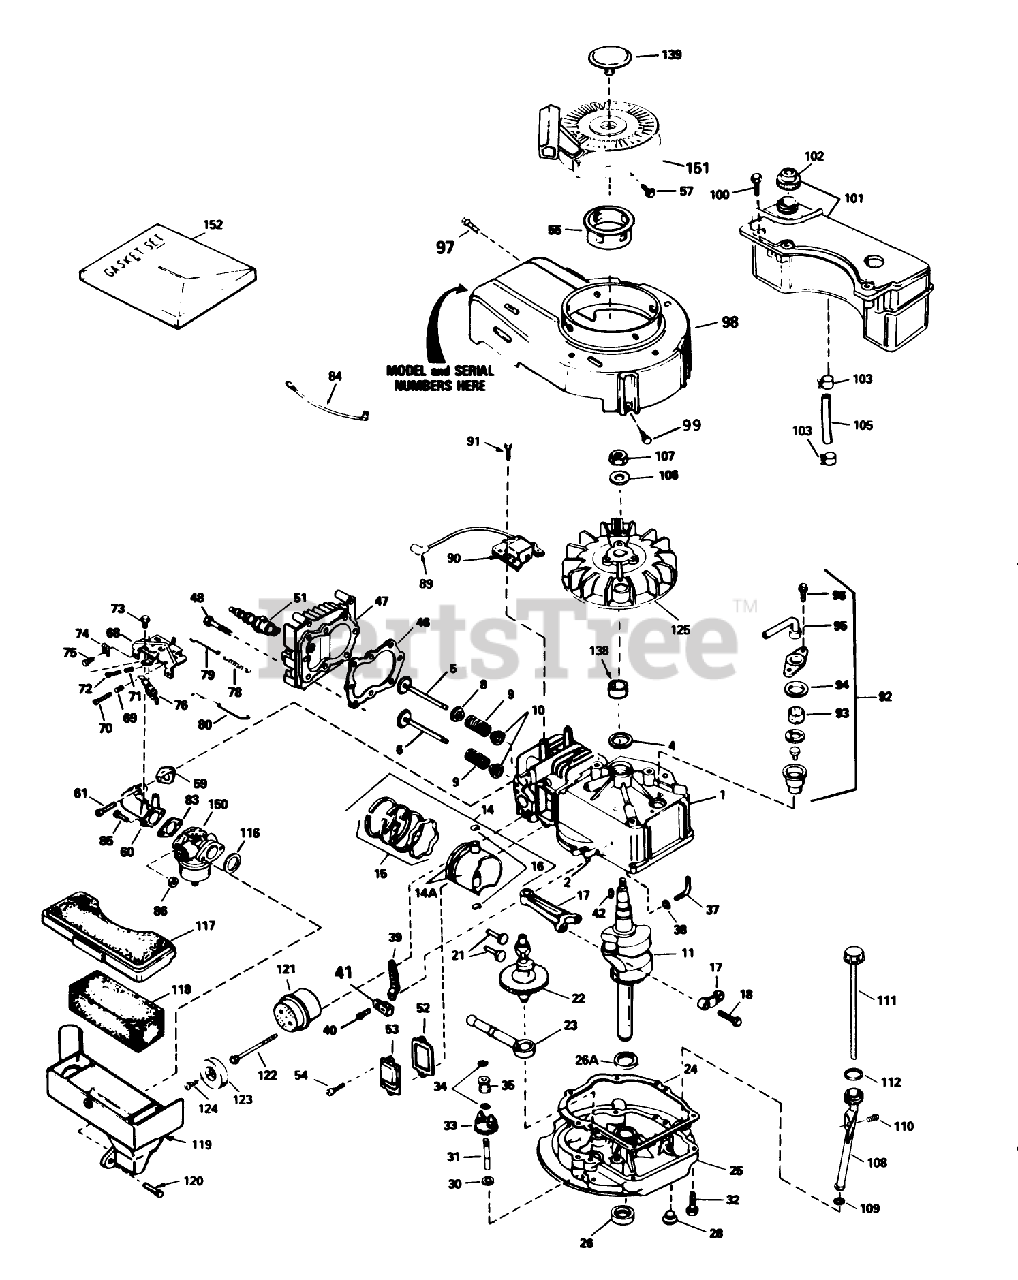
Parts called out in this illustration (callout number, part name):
1	Cylinder Assy. (Incl. #24)
2	Pin-Dowel
4	Seal-Oil
5	Valve, Intake (Std.) (Incl. Ref. #40)
5	Valve, Intake (1/32" oversize)(Incl. No. 40)
6	Valve, Exhaust (Std.)(Incl. No. 40)
6	Valve, Intake (1/32" oversize)(Incl. No. 40)
8	Seal Assy., Intake
9	Spring-Valve
10	Cap-Valve, Spring
11	Crankshaft
14	Piston-Pin Ring Assy. (Std.)(Incl. Ref. #16A, 17 18)
14	Piston-Pin Ring Assembly (.010 oversize)(Incl. Ref. #16A, 17 18)
14	Piston, Pin Ring Assy. (.020 Oversize)(Incl. Ref. #13A, 14, 15)
14A	Piston Pin Assy. (Std.)(Incl. Ref. #14)
14A	Piston Pin Assembly (.010 oversize)(Incl. Ref. #18)
14A	Piston Pin Assy. (.020 Oversize) (Incl. Ref. #14)
15	Ring Set-Piston (Std.)
15	Ring Set, Piston(.0100versize)
15	Ring Set (.020" OS)
16	Ring-Retaining, Piston Pin
17	Rod Assy., Connecting (Incl. Ref. #17)
18	Bolt-Rod, Connecting
21	Lifter-Valve
22	Camshaft(Mech.Comp. Release)
23	Oil Pump ASM
24	Gasket
25	Flange-Mounting (Incl. Ref. #26, 27 39)
26	Seal-Oil
26A	Washer-Thrust
28	Plug Oil Drain
30	Washer-Flat
31	Shaft-Governor
32	Screw (1/4-20 x 1-1/4)
33	Governor Gear ASM
34	Ring-Retaining
35	Spool-Governor
37	Rod, Governor (Incl. No. 36)
38	Washer-Flat
39	Governor Lever
40	Screw
41	Clamp-Lever, Governor
42	Key-Flywheel
46	63573 GIL 42 SNWTHW
47	Head-Cylinder
48	Screw (5/16-18x1-1/2)
51	Spark Plug-Resistor (R J19 L M)
52	Gasket-Breather
53	Cover-Valve
54	Screw
55	Hub-Starter
57	Screw, Hex Hd.
59	Gasket-Intake
60	Pipe-Intake (Incl. Ref. #59)
61	Screw (1/4-20 x 1)
68	Control Assy.-Remote Speed (Incl. Ref. #69 thru 72 76)
69	61709/GIL1515A/95-5
70	Screw
71	Spring-Compression
72	Screw
73	Screw (10-24 x 9/16)
74	Conduit
75	Screw (10-32 x 3/8)
76	Terminal
78	Spring Governor
79	2035A67 ADD.ASSEMBL
80	Link-Throttle
83	Gasket
84	Wire-Ground
86	Nut and Lock Washer (1/4-28)
89	Cover-Spark Plug
90	Solid State
91	Screw
92	Breather Assy. (Incl. Ref. #46 thru 51)
93	Element-Breather
94	Gasket-Breather
95	Tube, Breaker
96	Screw (10-24 x 9/16)
97	Screw (10-24 x 9/16)
98	Housing-Blower
99	Screw (1/4-20 x 1/2)
100	Screw (10-32 x 35/64)
101	Tank Assembly-Fuel (Incl. Ref. #102)
102	Cap-Fuel
103	Clamp-Line, Fuel
105	Line-Fuel
106	Washer-Belleville
107	Nut-Flywheel
108	Oil Fill Tube
109	Gasket
110	Screw (10-32 x 1/2)
111	Dipstick
112	55063 SNWTHWR ADD.W
116	Gasket-Cleaner, Air
117	Cover-Air Cleaner
118	Filter-Air Cleaner
119	Body Air cleaner
120	Screw
121	B Muffler (Incl. Ref. #122)
122	Screw
123	Cover-Muffler
124	Screw (8-32 x 3/8)
125	Flywheel
138	Spacer
139	Plug Starter
150	Carburetor (Incl. Ref. #83)
151	Starter-Rewind
152	Gasket Set
